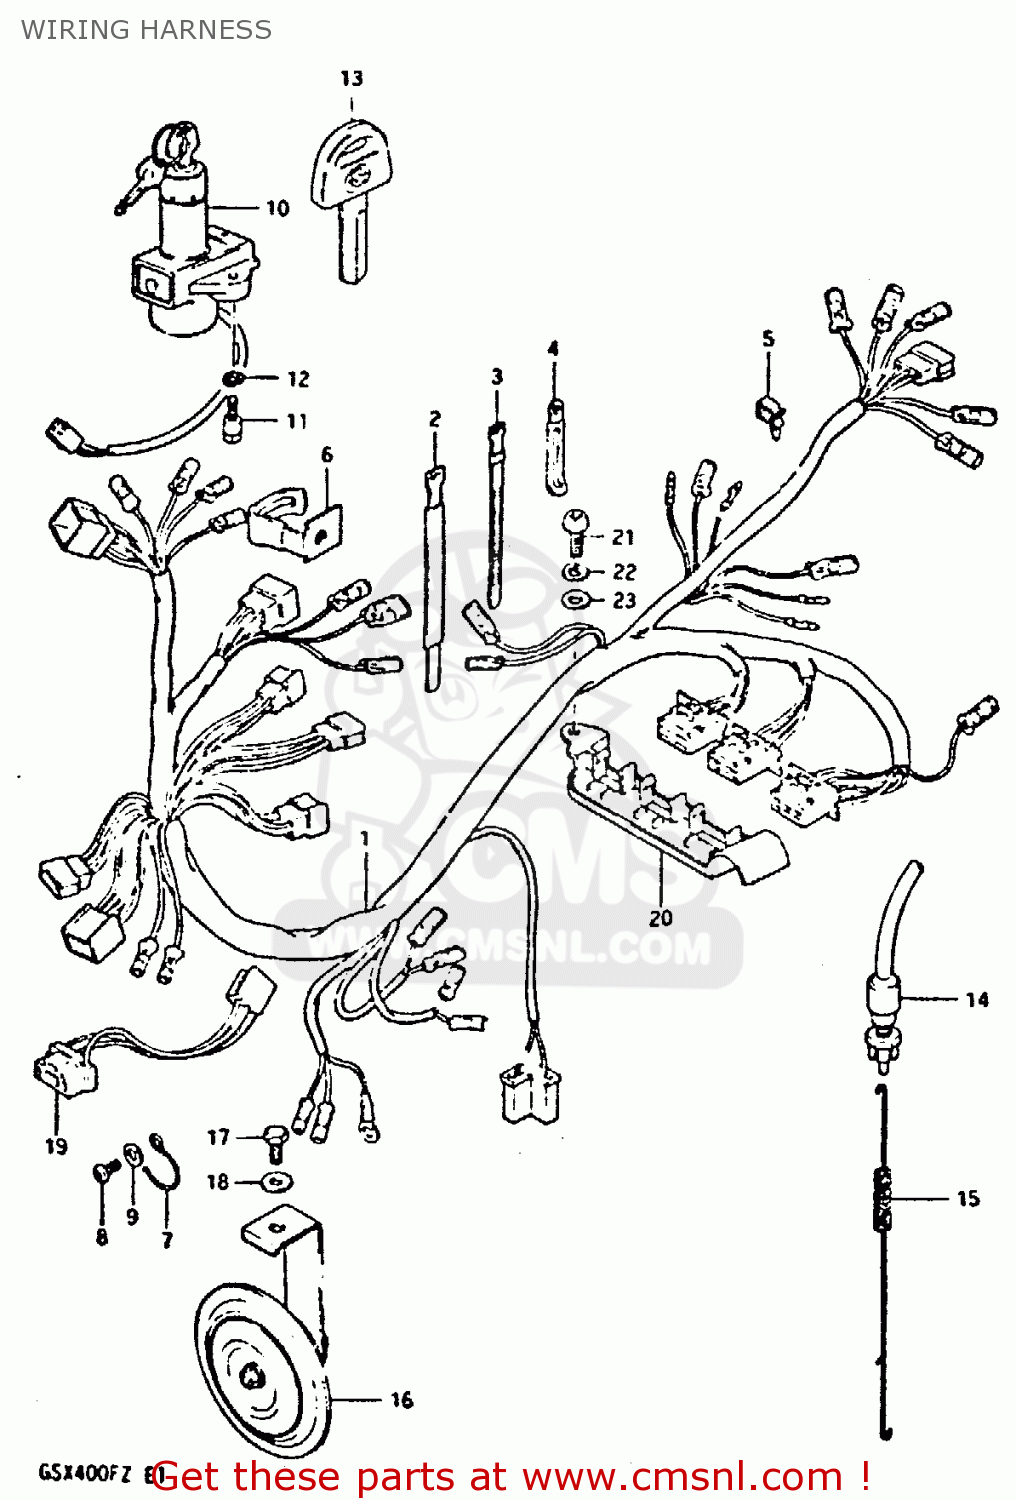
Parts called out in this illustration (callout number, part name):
1	WIRING HARNESS
2	CLAMP
3	CLAMP(L:80)
4	CLAMP
5	CLIP
6	CLAMP,WIRING HARNESS
7	GUIDE,WIRING HARNESS
8	SCREW 6X12
9	WASHER
10	SWITCH ASSY,IGNITION
11	BOLT
12	LOCK WASHER
13	KEY,BLANK
14	SWITCH ASSEMBLY,STOP LAMP
15	SPRING
16	HORN
17	BOLT 8X12
18	WASHER
19	LEAD WIRE,HEADLAMP
20	PLATE, COUPLER
21	BOLT
22	LOCK WASHER
23	WASHER
